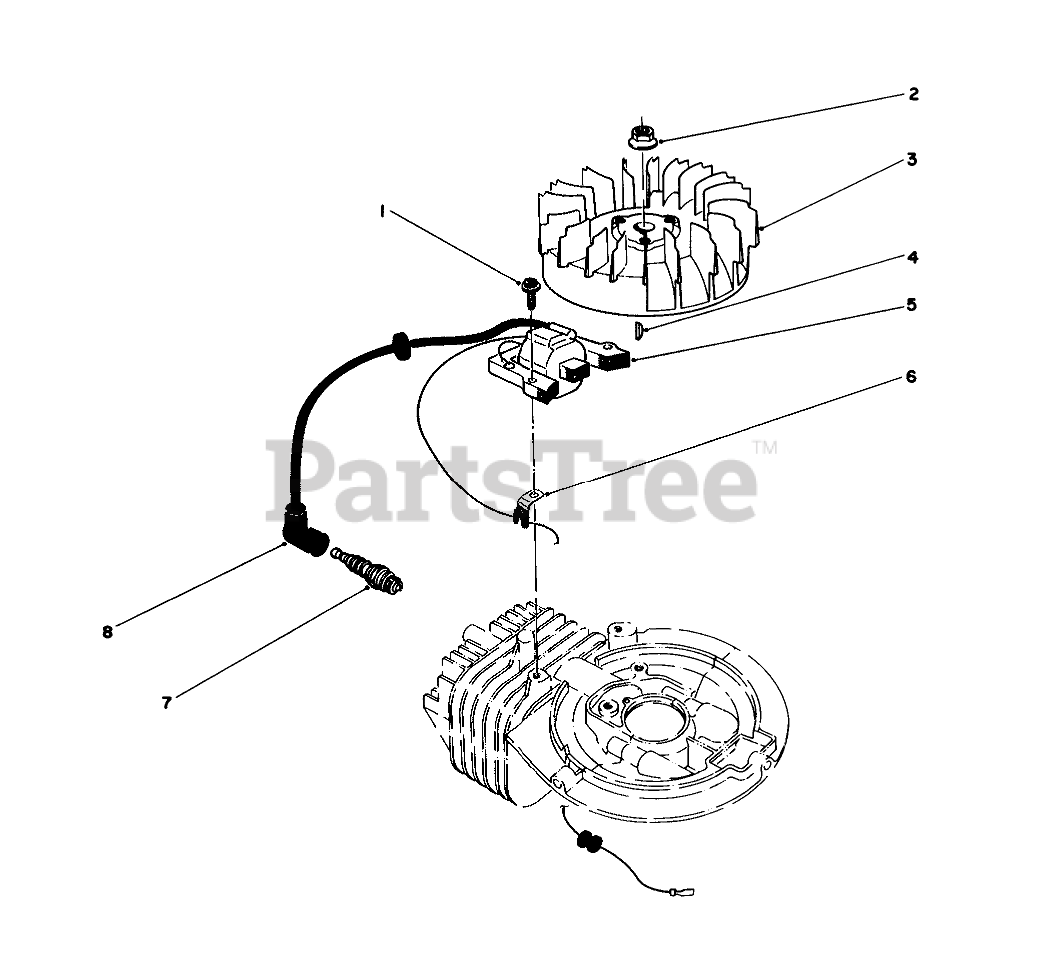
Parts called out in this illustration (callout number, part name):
1	Allenhead
3	FLYWHEEL
5	COIL-MAGNETO
6	CLAMP
7	Sparkplug
8	CAP-SPARKPLUG
